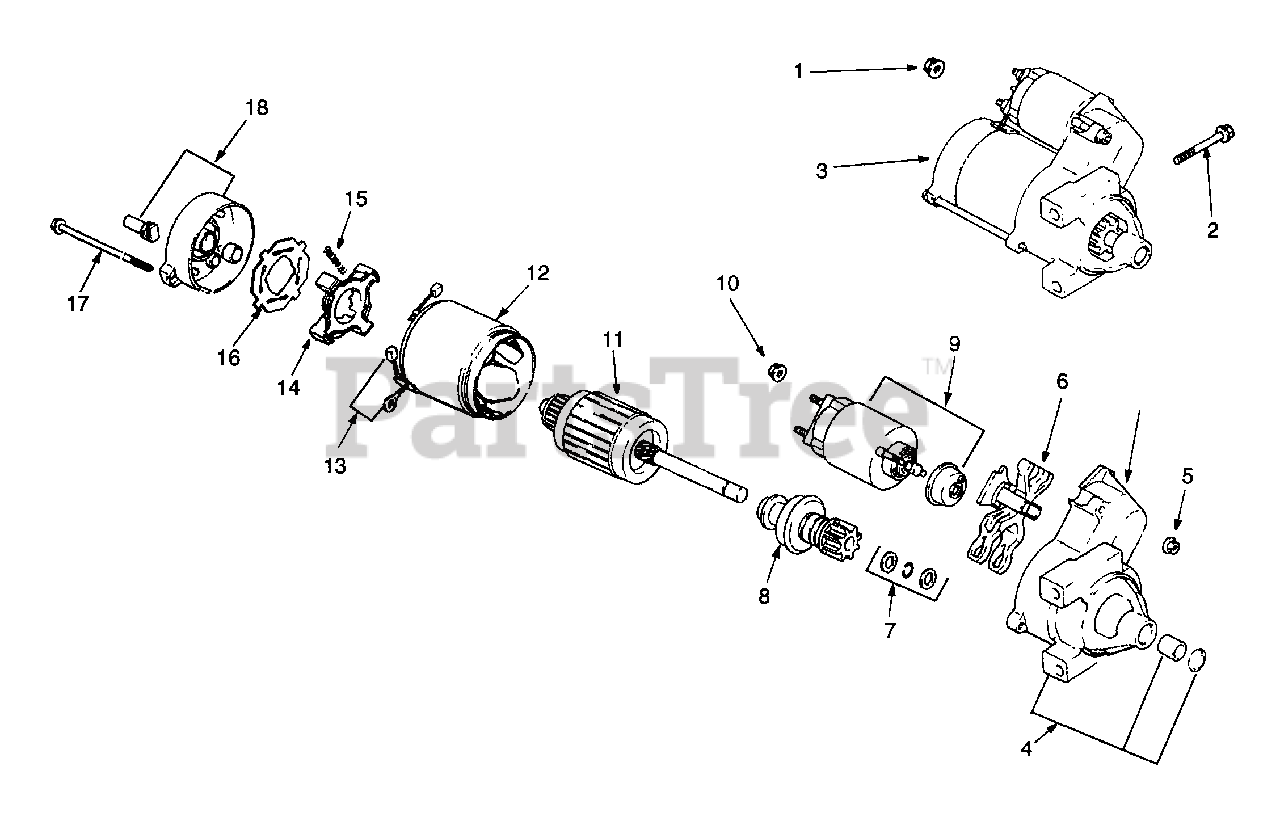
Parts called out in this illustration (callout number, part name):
1	Nut, Hex Flange M8 x 1.25"
2	Screw, Hex Flange M8 x 1.25 x 80
3	Starter, Solenoid Shift Assembly
4	Drive, End Cap
5	Nut, Starter
6	Lever, Starter Drive
7	Kit, Starter repair
8	Drive, Pinion
10	Nut, Starter
11	Armature, Starter
13	Kit, Brush & Spring
14	Holder, Brush
15	Spring, Brush
18	Commutator, End Cap
